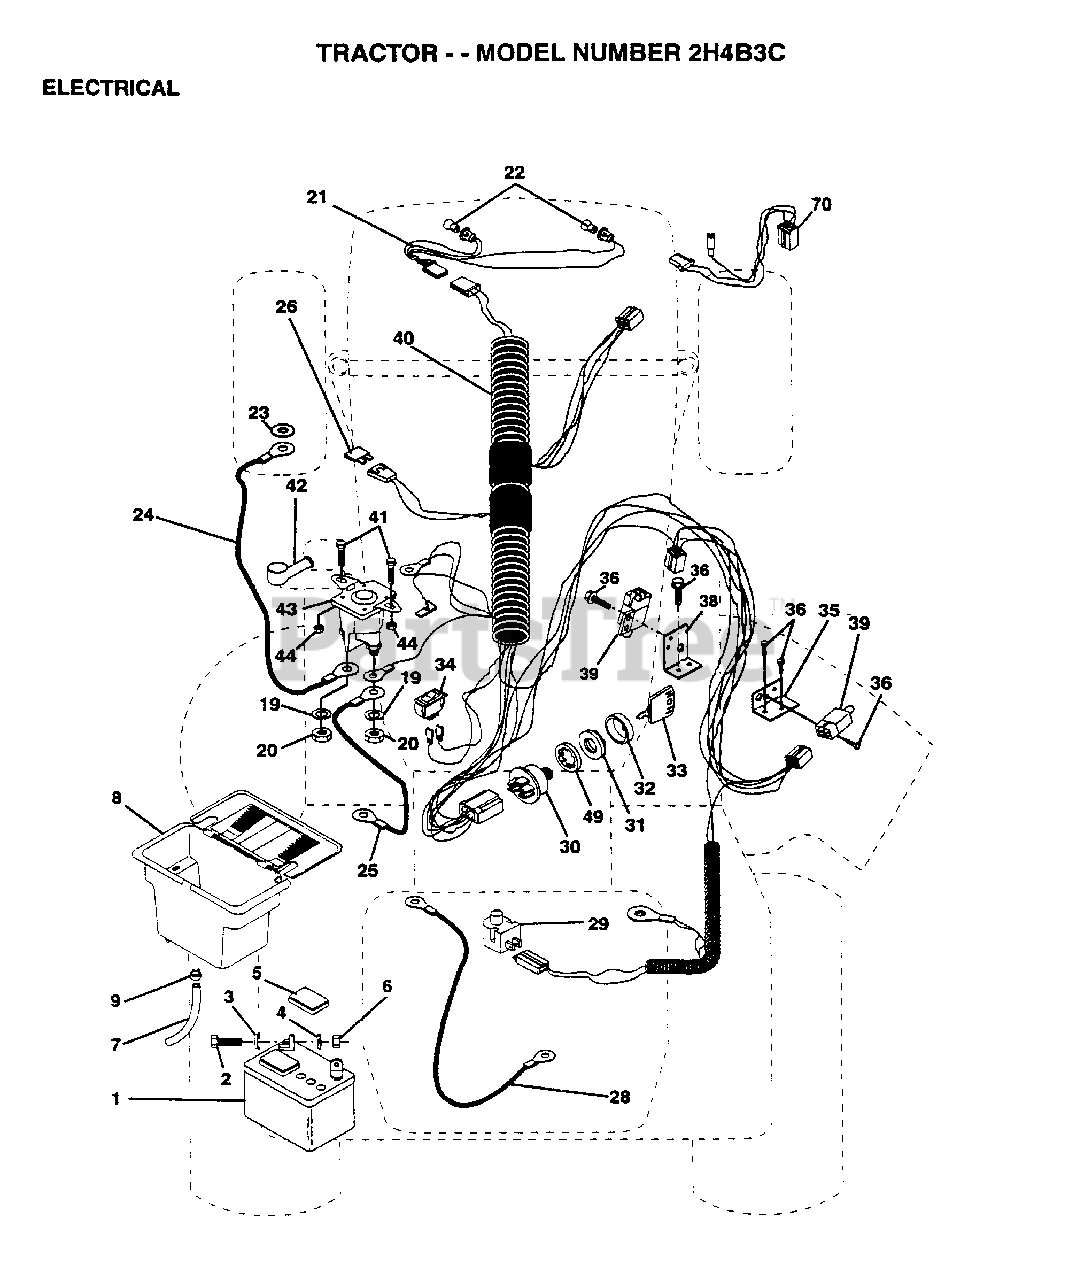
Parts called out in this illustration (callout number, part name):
2	BOLT LT
3	WASHER
4	LOCKWASHER
5	"CAP,BATTERY "
7	TUBE T
9	HOSE CLAMP T
20	NUT
21	"HARNESS,LIGHT SOC"
22	HEADLAMP BULB
23	LOCKWASHER
24	"CABLE T, BATTERY"
26	FUSE HYT
28	CABLE T
29	SWITCH SEAT
32	COVER KEY SWITCH
33	KEY MLD GEN DELTA
34	SWITCH LT
35	BRACKET LT
36	SCREW
38	BRACKET SWITCH IN
39	SWITCH INTERLOCKT
40	HARNESS IGN DASH
41	BOLT HXHD FIN
44	NUT HXKEP 1/4X20
49	LOCKWASHER
70	HARNESS ENG DUAL
